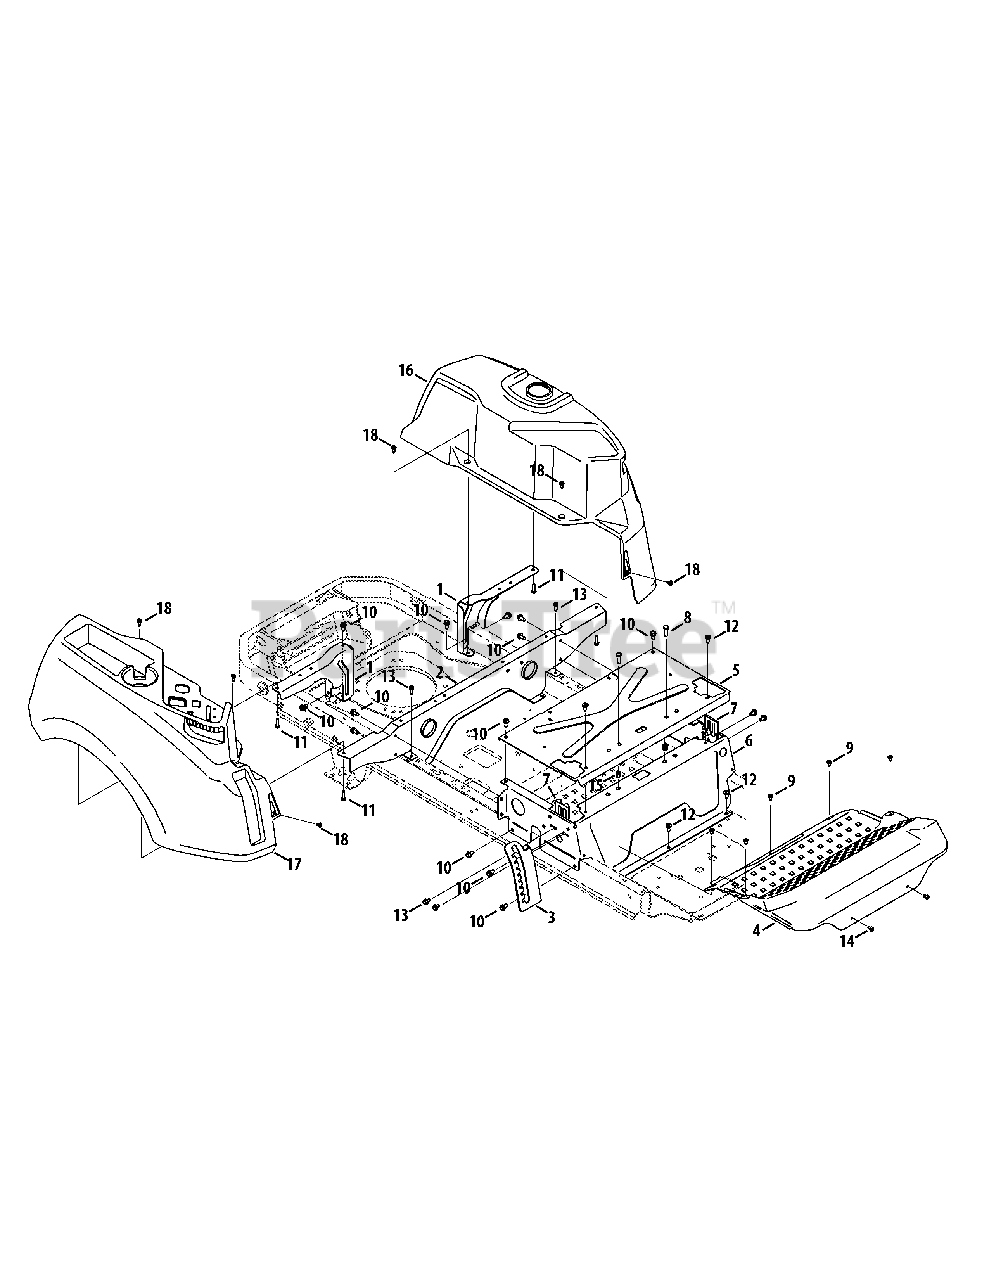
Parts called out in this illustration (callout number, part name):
1	Rear Tank Bracket
2	Rear Seatbox Brace
3	Height Index Bracket
4	Floor Board
5	Seatbox Plate
6	Seat Frame
7	Lapbar Brace Bracket
8	Hex Cap Screw 5/16-18 x 1.00
9	Self Tapping Screw 1/4-20 x .50
10	Hex Washer Screw 5/16-18 x .750
11	Hex Washer Screw 5/16-14 x 1.00
12	Self Tapping Screw 5/16-18 x .750
13	Hex Washer Screw 5/16-18 x .50
14	Self-Tapping Screw 5/16-18, 0.750
15	Nut 5/16-18
16	LH Console
17	RH Console
18	Shoulder Screw 1/4-20
